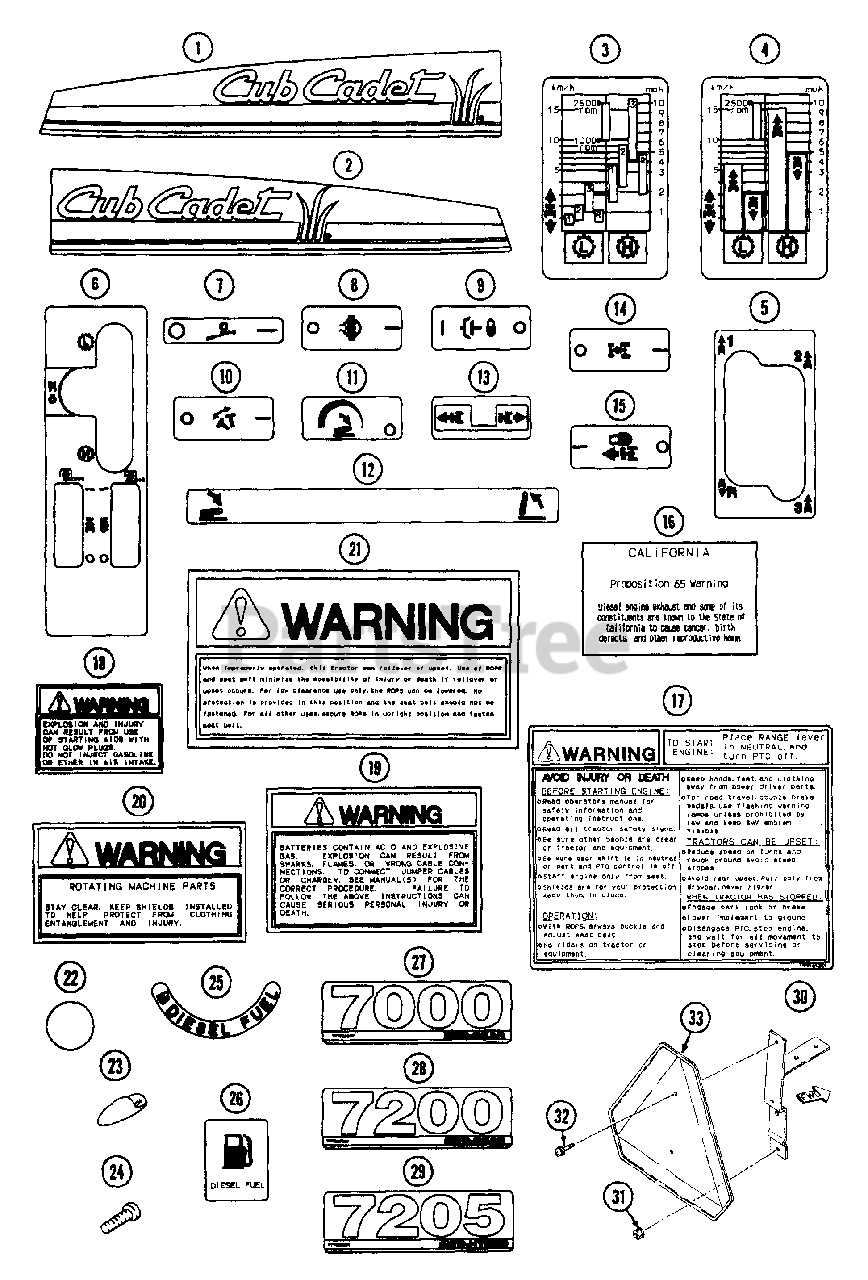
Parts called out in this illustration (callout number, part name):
1	Label, Side L.H.
2	Label, Side R.H.
3	Label, Speed G
4	Label, Speed H
8	Label, Diff Lock
9	Label, Declutch
11	Label, D.R. Cont
12	Label, Position
13	Label, HST Cont
15	Label, Sp Cont
16	Label, Propositi
17	Label, Warning
18	Label, Warning
19	Label, Warning
20	Label, Warning
21	Label, Warning
27	Label, Model
29	Label, Model
33	Emblem, SMV
